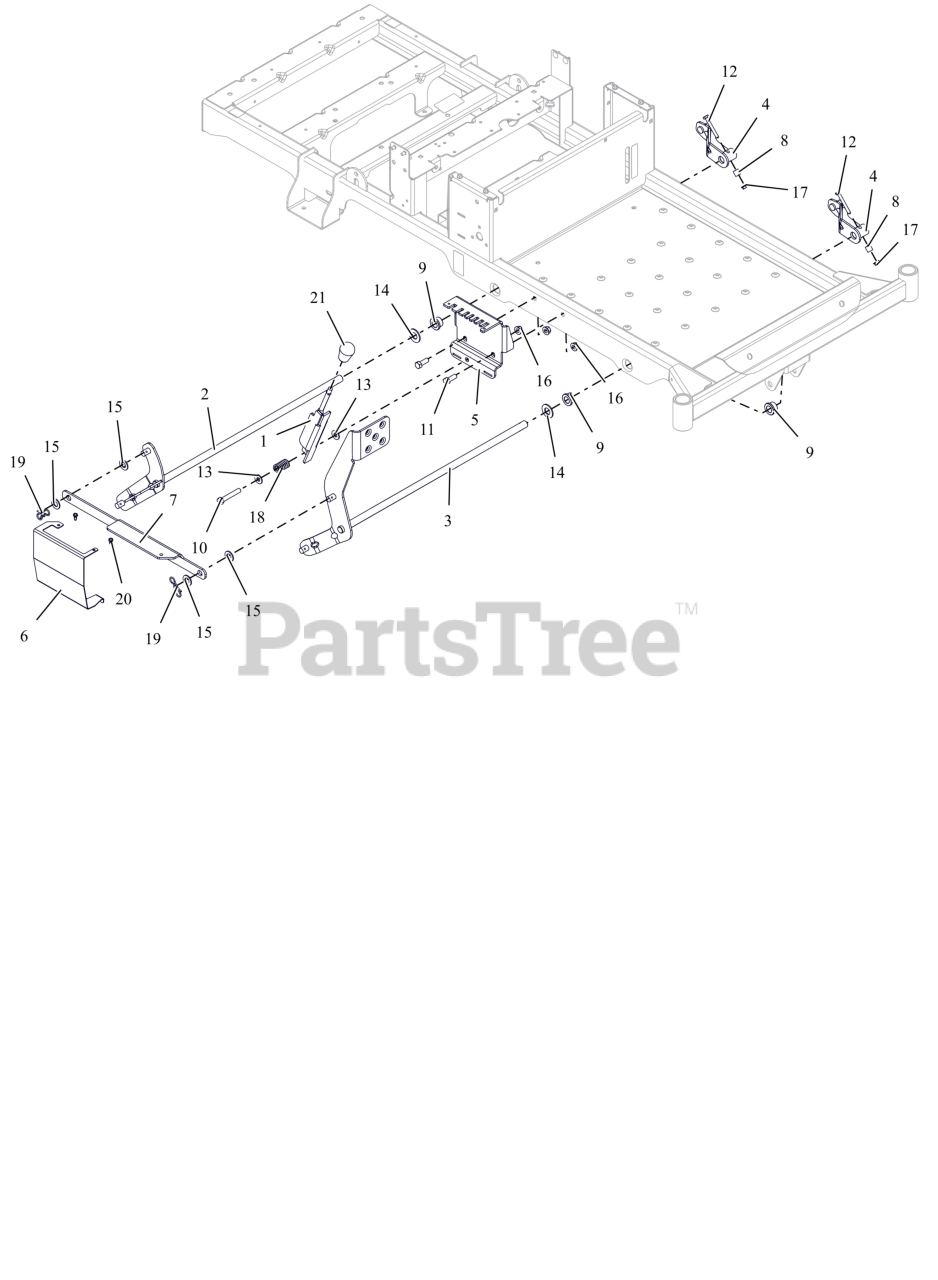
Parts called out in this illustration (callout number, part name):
1	WLDMT, HEIGHT OF CUT (RED)
2	WLDMT, REAR DECK LIFT (RED)
3	WLDMT, FOOTPEDAL (RED)
4	WLDMT, DECK LIFT ARM
5	PLATE, HEIGHT ADJUSTMENT (RED)
6	GUARD, DECK HOC (RED)
7	LINK, LIFT /HOC (RED)
8	BSHG-SLV .265X.500X.500
9	BSHG-FLG .629X.879X.469X1.250
10	BLT,HEX .38-16X2.25 G5 ZCC
11	BLT,HEX .38-16X1.00 G5 ZCC
12	BLT, HEX .25-20X2.00 G5 ZCC
13	WSHR,FLT .375X.875X.083 ZCC
14	WSHR, FLT .656X1.313X.095 ZCC
15	WSHR-FL-NYL .518X1.000X.080
16	NUT-LK-CTR-FLG .375-16 GF ZCC
17	NUT-LK-CTR-FLG .25-20 ZC120
18	SPRG, COMPRESSION
19	PIN, BOWTIE .091X1.875 ZCC
20	SCR,TAP #10-24X.50 HWH TR ZCC
21	KNOB,SOFT TEARDROP,PUSH-ON BLK
